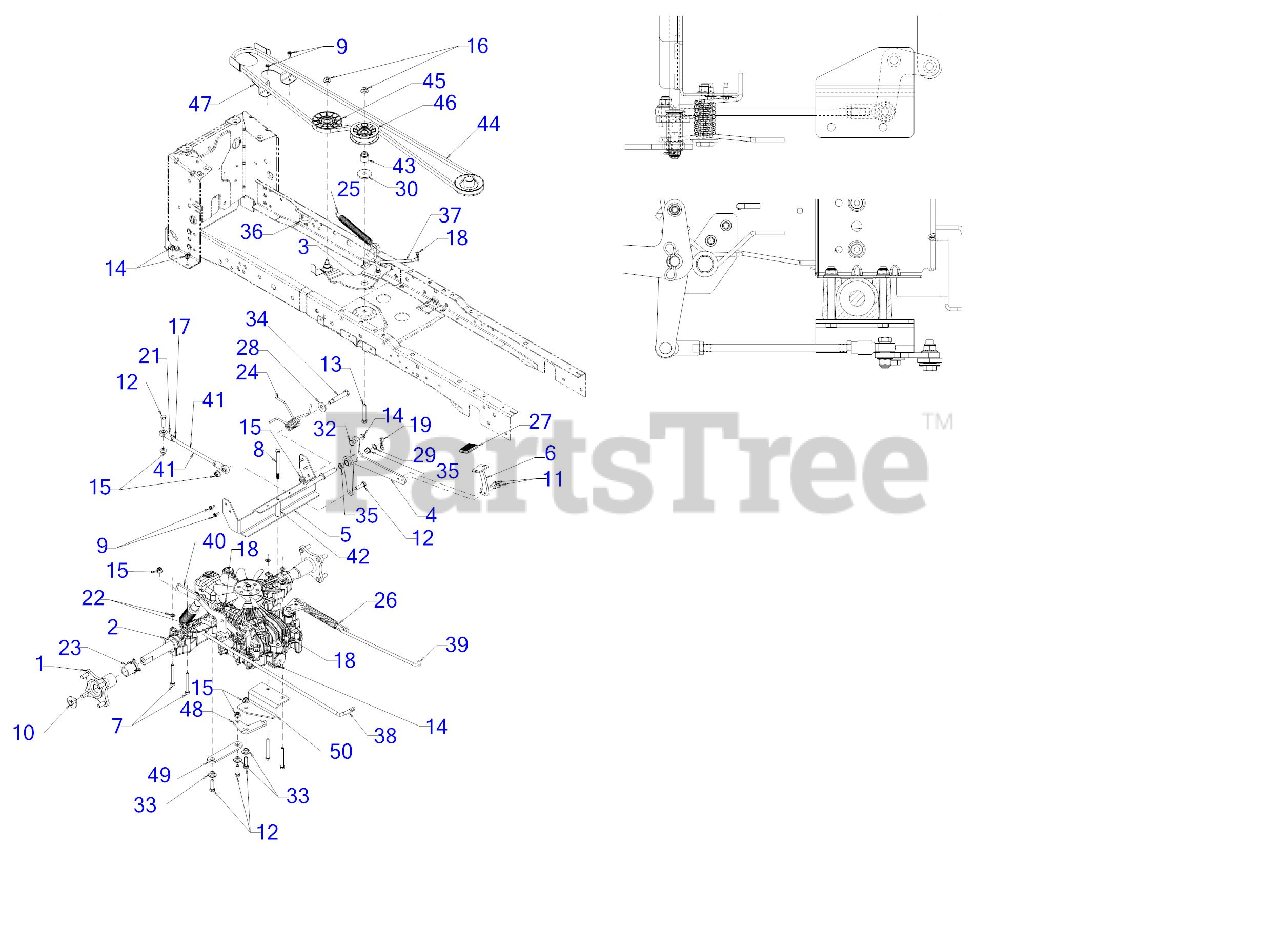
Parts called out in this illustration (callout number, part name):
1	WHEEL HUB ASSEMBLY
2	HYDRO TRANS ASSEMBLY
3	IDLER BRACKET ASSEMBLY
4	DIFF PEDAL PIVOT ASSEMBLY (PLATED)
6	DIFF LOCK PEDAL ASSEMBLY (PLATED)
7	HEX SCREW 5/16-18 x 2.75
8	HEX SCREW 5/16-18 x 4.00
9	SCREW M6-1 x .625
10	SCREW 3/8-16 x .75 GR5.1
11	SCREW 1/4-20 x .750
12	SCREW 3/8-16 x 1.25 GR5
13	SCREW 3/8-16 x 2.25 GR5
14	FLANGE LOCK NUT 5/16-18
16	FLANGE LOCK NUT
17	HEX JAM NUT 3/8X24
18	BOW TIE COTTER PIN 1/4-5/16
19	BOW TIE COTTER PIN
21	ROD END 3/8 ID
22	PUSH NUT
23	AXLE SLEEVE 1.02 ID x 1.60 LG
24	DIFF PEDAL TORSION SPRING
25	EXTENSION SPRING .790 DIA x 8.41
26	EXTENSION SPRING 0.90 DIA x 8.14
27	DIFF LOCK PEDAL PAD
28	FLAT WASHER
29	THRUST WASHER
30	SHOULDER SPACER
32	SHOULDER SCREW
33	SHOULDER SPACER
34	SHOULDER SCREW .50 x 2.23 3/8-16
35	NYLINER BEARING
36	DECK SPRING HOOK
37	IDLER BRACKET LINK ROD
38	HYDRO CONTROL ROD (PLATED)
39	BRAKE CONTROL ROD (PLATED)
40	HYDRO DISENGAGE ROD (TUFF TORQ)
41	ROD .375 OD X 8.75 LG (PLATED)
43	SHOULDER SPACER
44	V-BELT A SEC X 90.00
45	V-IDLER PULLEY 3.56 OD
46	FLAT IDLER PULLEY 3.00 OD
48	PIVOT BELLCRANK (PLATED)
49	BELLCRANK LINK (PLATED)
50	BELLCRANK MOUNTING BRACKET (PLATED)
